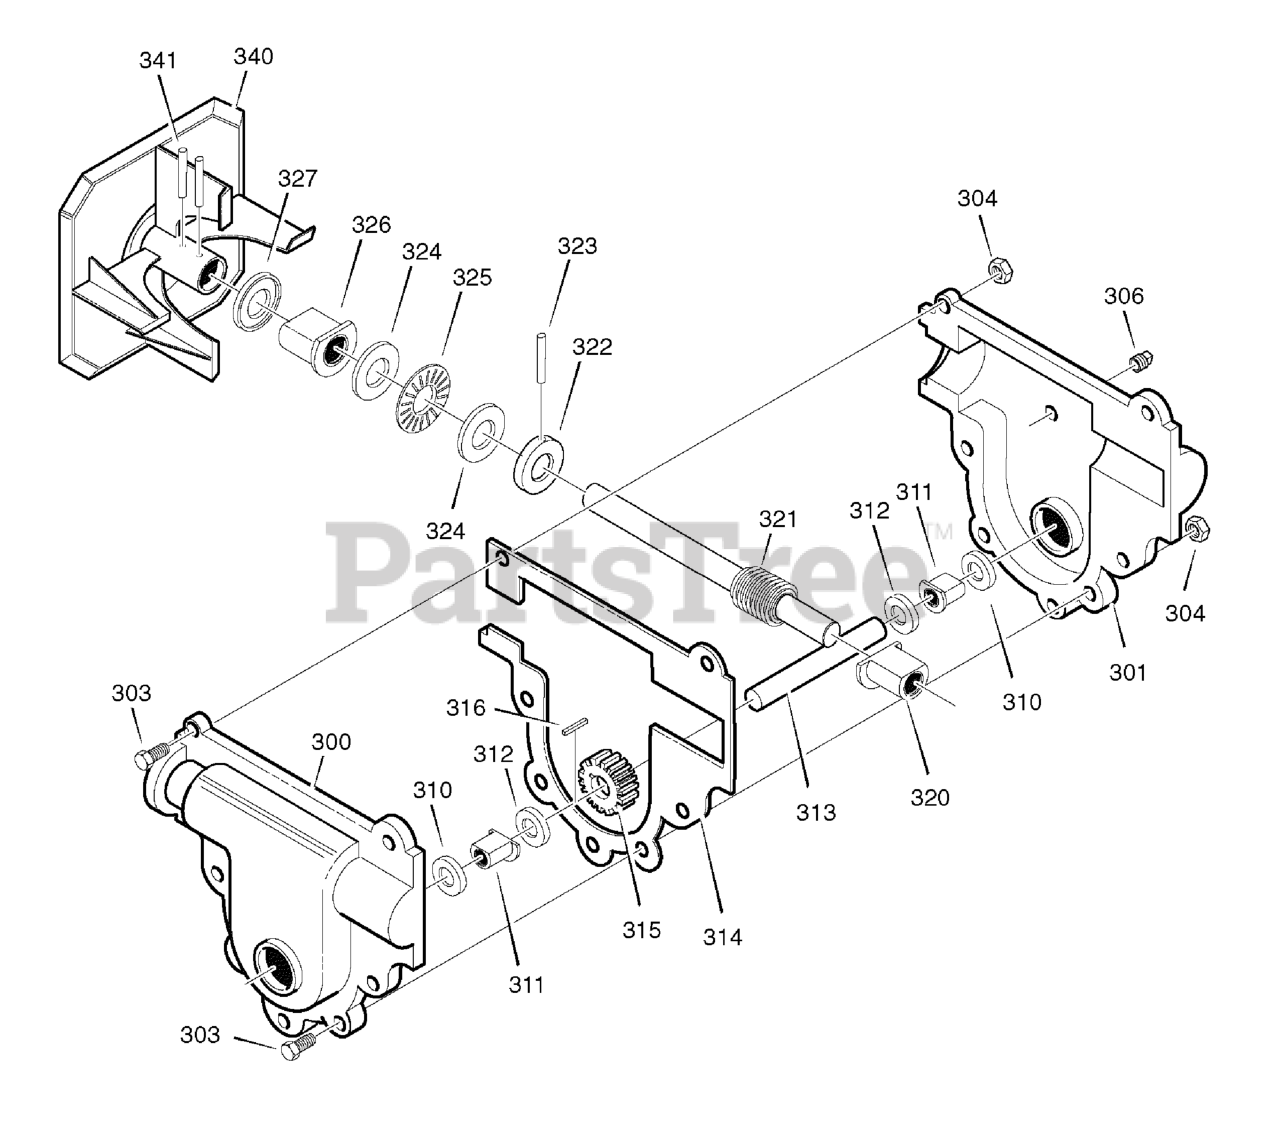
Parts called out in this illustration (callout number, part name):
300	CASE, Gear R.H.
301	CASE, Gear L.H.
303	SCREW, 1/4 - 20 x 3/4
304	NUT, 1/4 - 20
306	SCREW, 3/8-16 x 1/2
310	SEAL, Oil
311	BEARING, Flange
312	WASHER, Flat
313	SHAFT, Auger Output
314	GASKET, Gear Box
315	GEAR, Worm
316	KEY, Woodruff
320	BEARING, Flange
321	SHAFT, Auger Input
322	COLLAR, Thrust
323	PIN, Spring
324	WASHER, Flat
325	BEARING, Roll
326	BEARING, Flange
327	SEAL, Oil
340	IMPELLER
341	PIN, Spring
